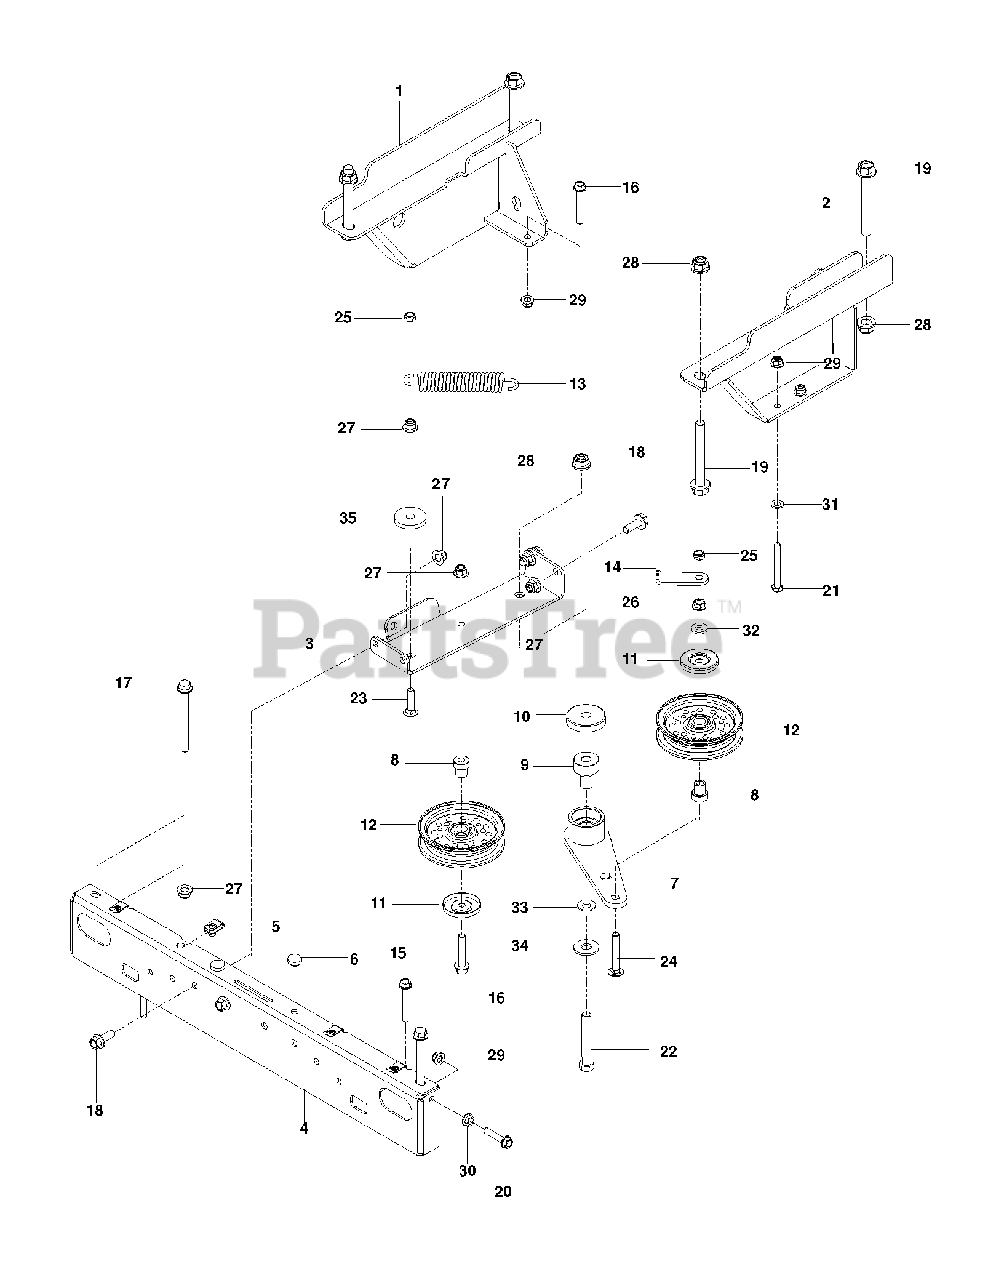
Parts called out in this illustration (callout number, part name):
1	MOUNT.ZT3400.RT.BLACK
2	MOUNT.ZT3400.LT.BLACK
3	MOUNT IDLER BLK
4	MOUNT FT ZT3400 BLK
5	U-CLIP 5/16-18 NUT RETAINER
6	GROMMET, BUMPER
7	ARM, IDLER, STEEL, W/BGS
8	PIVOT, IDLER
9	PIVOT, BEARING
10	SHIELD, DUST
11	DUST SHIELD
12	IDLER PULLEY
13	SPRING, EXTENSION
14	BRACKET, SPRING
15	HHFS 3/8-16 X 2.0 GD 5
16	HHFS 5/16-18 X 2.25 GD 5
17	HHFS 3/8-16 X 4 GR5 ZD
18	HHFS 3/8-16 X 1 GRD 5 ZD
19	HHFS 1/2-13 X 4.0 GD8 ZD
20	HHFS 5/16-18 X 1.5 GD 5
21	HCS 5/16C X 2-3/4
22	HCS 1/2C X 3 1/4
23	RHSNB, 3/8-16 X 1-1/2
24	CARRIAGE BOLT 3/8-16 X
25	NUT HEX 3/8-16 NYLON, THIN
26	NUT 3/8C WHIZ
27	NUT 3/8-16 HEX FLG NYLOC ZD
28	NUT, 1/2-13 HEX FLG NYLOC ZD
29	5/16-18 NYLOC FLANGE NUT
30	NUT 5/16C WHIZ
31	FLAT WASHER 5/16 SAE
32	WASHER, 3/8 THICK
33	CONTACT BELLSPR 1/2
34	WASH USS FLAT 1/2
35	SPINDLE WASHER
